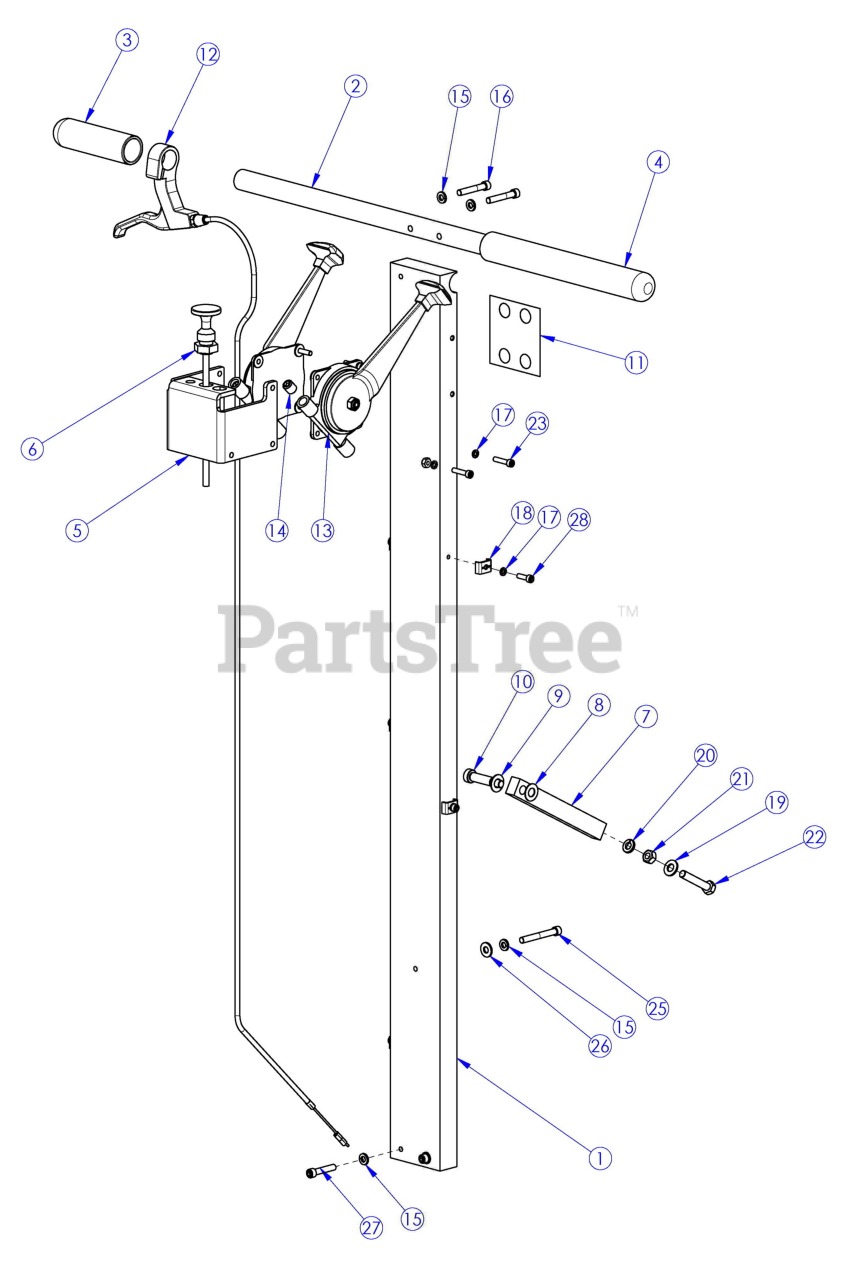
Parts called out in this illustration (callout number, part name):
1	Handle, X750
2	Handle Bar
3	Grip, Foam Handle, 4.5"L Black
4	Grip, Foam Handle, 9.5"L Black
5	Bracket, Control Mount
6	Lock Throttle W/Cable
7	Pump Release Arm
8	Washer, 3/8" Delrin
9	Washer, 3/8"X .03"Thk Flat S.S.
10	Shsb, 3/8 X 1 1/4
11	Label, Guide/Speed Control
12	Kit, Blade Release, X750
13	Control Lever Assy
14	Set Screw, Cup .438-20 X .500
15	Washer, Split 1/4" S.S.
16	Shcs 1/4-20 X 1 1/2 S.S.
17	Washer, Split #10 S.S.
18	Clamp, Metal
19	Washer, 5/16" Flat Sae Cad
20	Washer, Split 5/16" S.S.
21	Nut, 5/16-18 Hex, Gr5 Zinc
22	HHB 5/16-18 X 1.75 Gr8
23	Shcs 10-32 X 7/8 Blk
24	Nut, Nyloc, #10-32 S.S.
25	Shcs 1/4-20 X 2 S.S.
26	Washer, 1/4" Flat S.S.
27	Shcs 1/4-20 X 1 1/4 S.S.
28	Shcs 10-32 X 5/8 S.S.
